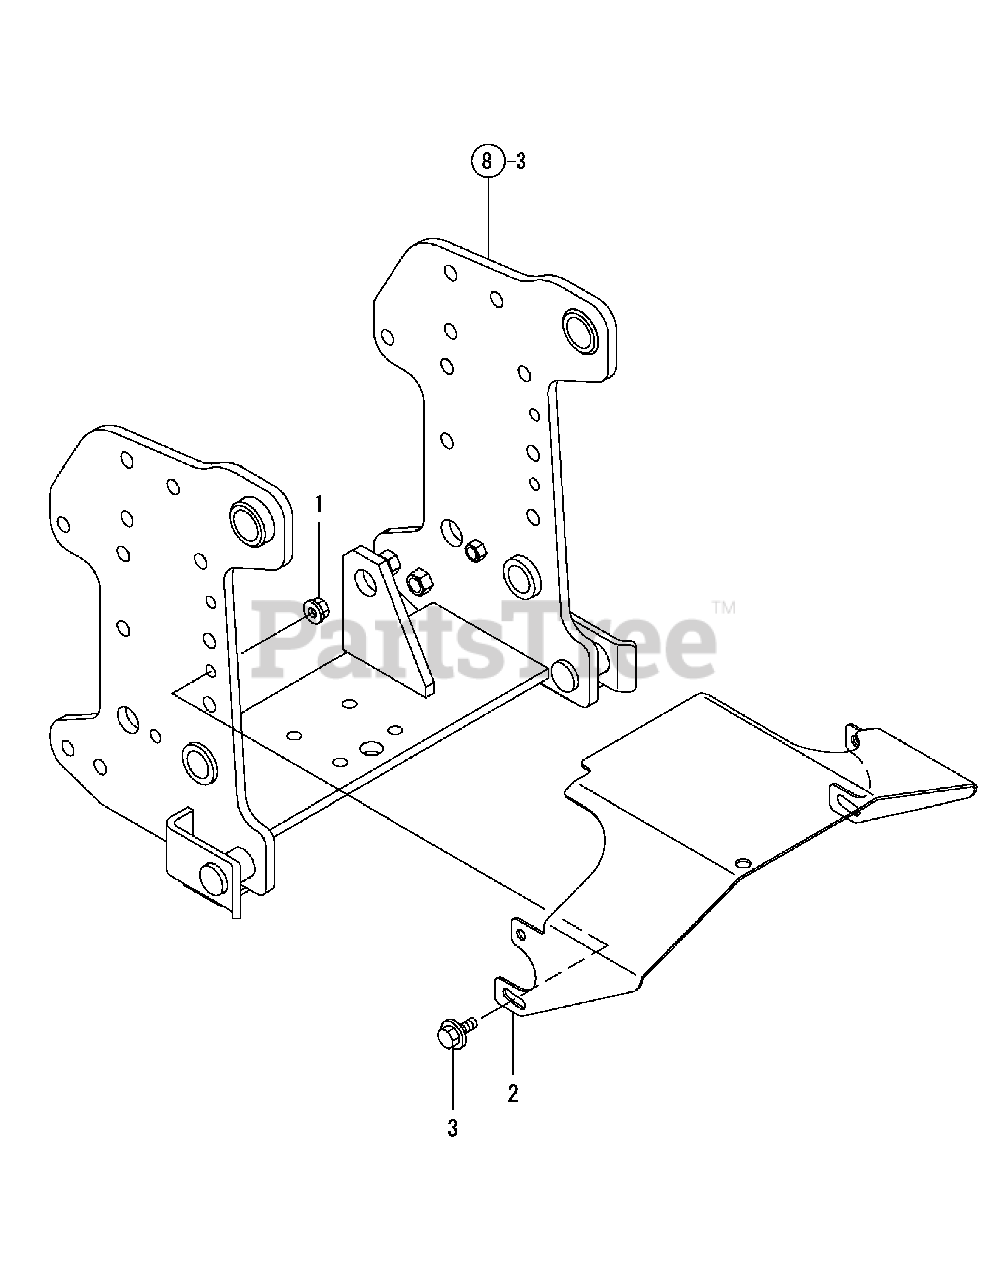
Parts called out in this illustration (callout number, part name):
1	NUT W/WASHER 8
2	COVER M ASSY, PTO.
3	BOLT M 8X 30 PLATED
